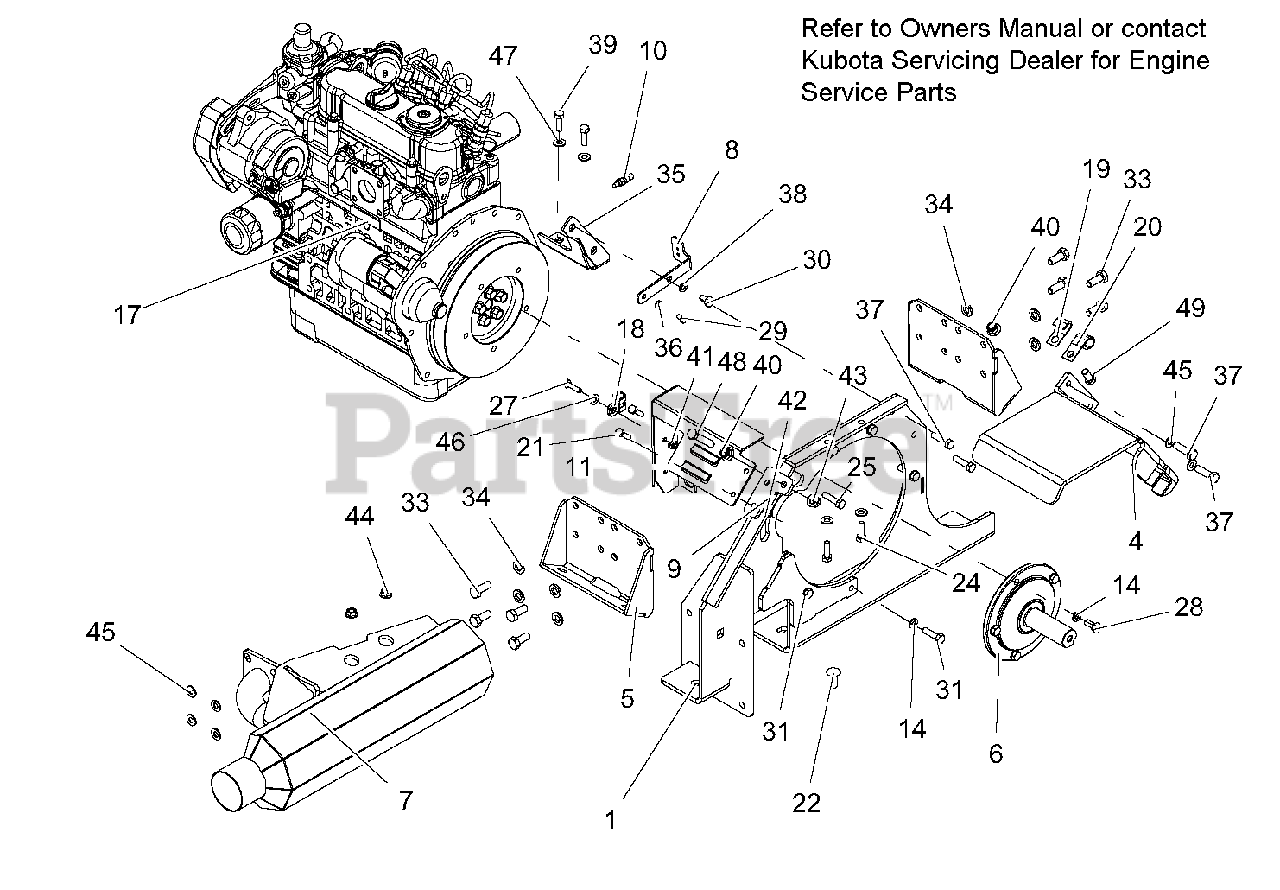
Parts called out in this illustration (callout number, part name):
1	WLDMT, ENGINE /GEARBOX MNT-BLACK
4	WLDMT, DIESEL CLUTCH STOP-BLACK
5	WLDMT, FRONT ENGINE MOUNT
6	SHAFT, STUB KUBOTA DIESEL MACHINED
7	MFLR, DIESEL PT-400
8	BRKT, THROTTLE CABLE
9	SPRG, ANCHOR
10	SENDER, WATER TEMPERATURE
11	BRKT, HEAT DEFLECTOR LOUVERED
14	WSHR, LOCK M8 YWZC
17	KUBOTA_D902_E3B_WITHOUT_RADIATOR
18	CLAMP, CUSHIONED STEEL
19	, J-CLAMP
21	BLT-HEX .25-20X1.00 GR5 YWZC
22	@BLT-RDHDSQNK .38-16X1.00 G5 YWZC
24	BLT-HEX .31-18X1.00 GR5 YWZC
25	BLT-HEX .38-16X2.00 GR8 YWZC
27	BLT-HEX .25-20X1.00 GR5 YWZC
28	@BLT-HEX M8-1.25X20 YWZC
29	BLT-HEX M6 X 1.0X10 YWZC
30	@BLT-HEX M8 X 1.25X14 YWZC
31	@BLT-HEX M8 X 1.25X30 GR5 YWZC
33	BOLT, HEX M10-1.25 X 25 YWZC
34	@WSHR-LK .44X.109 REG YWZC
35	WLDMT, DIESEL FUEL FILTER MOUNT
36	@WSHR-LK .25X.062 REG YWZC
37	BLT-HEX .31-18X1.25 GR5 YWZC
38	@WSHR-LK .31X.078 REG YWZC
39	BLT-HEX .31-18X1.00 GR5 YWZC
40	NUT-LK-NYL-FLG .38-16 YWZC
41	NUT-LK-NYL-FLG .25-20 YWZC
42	NUT-LK-NYL-FLG .25-20 YWZC
43	@NUT-SPNLK-FLG .375-16 YWZC
44	@NUT-SPNLK-FLG .312-18 YWZC
45	@WSHR-FL-STL.344X.688X.065YWZC
46	@WSHR-FL-STL.281X.62X.065 YWZC
47	@WSHR-FL-STL.344X.688X.065YWZC
48	BLT-HEX .38-16X2.00 GR8 YWZC
49	BLT-HEX .38-16X.75 GR5 YWZC
